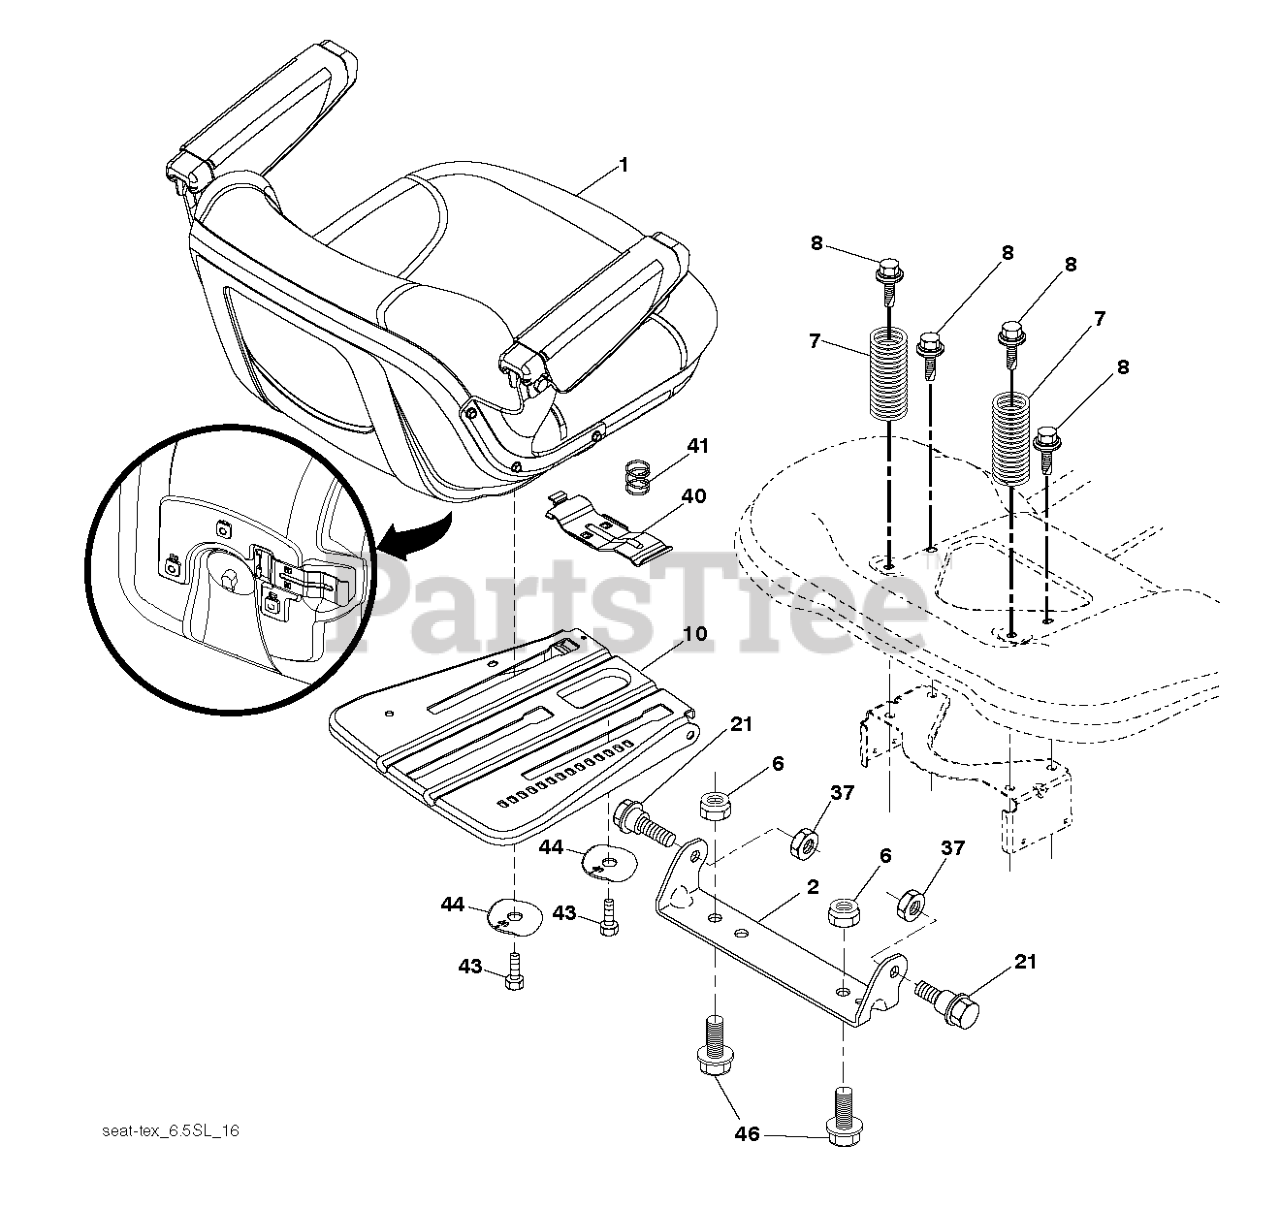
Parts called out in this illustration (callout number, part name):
1	SEAT.TH154.498GY.HUS.ARMRESTS
2	BRKT.PIVOT.FENDER
6	NUT
7	SPRING.COMPRESS.SEAT.TAPERED
8	BOLT.5/16-18UNCX3/4 W/SEMS.BLK
10	PLATE.PNT.SEAT.SLIDE.3PT.EDIP
21	BOLT.5/16-18X5/8.SHOULDER
37	NUT.71038.31-18.HEX.NYLOCK
40	HANDLE.SLIDE.SEAT.TEX.GREY
41	SPRING.LATCH.SEAT.TEX
44	WASHER.WINGED.3/8ID.1.5OD
46	BOLT.3/8-16X1;1.25OD.WSHR.SEMS
